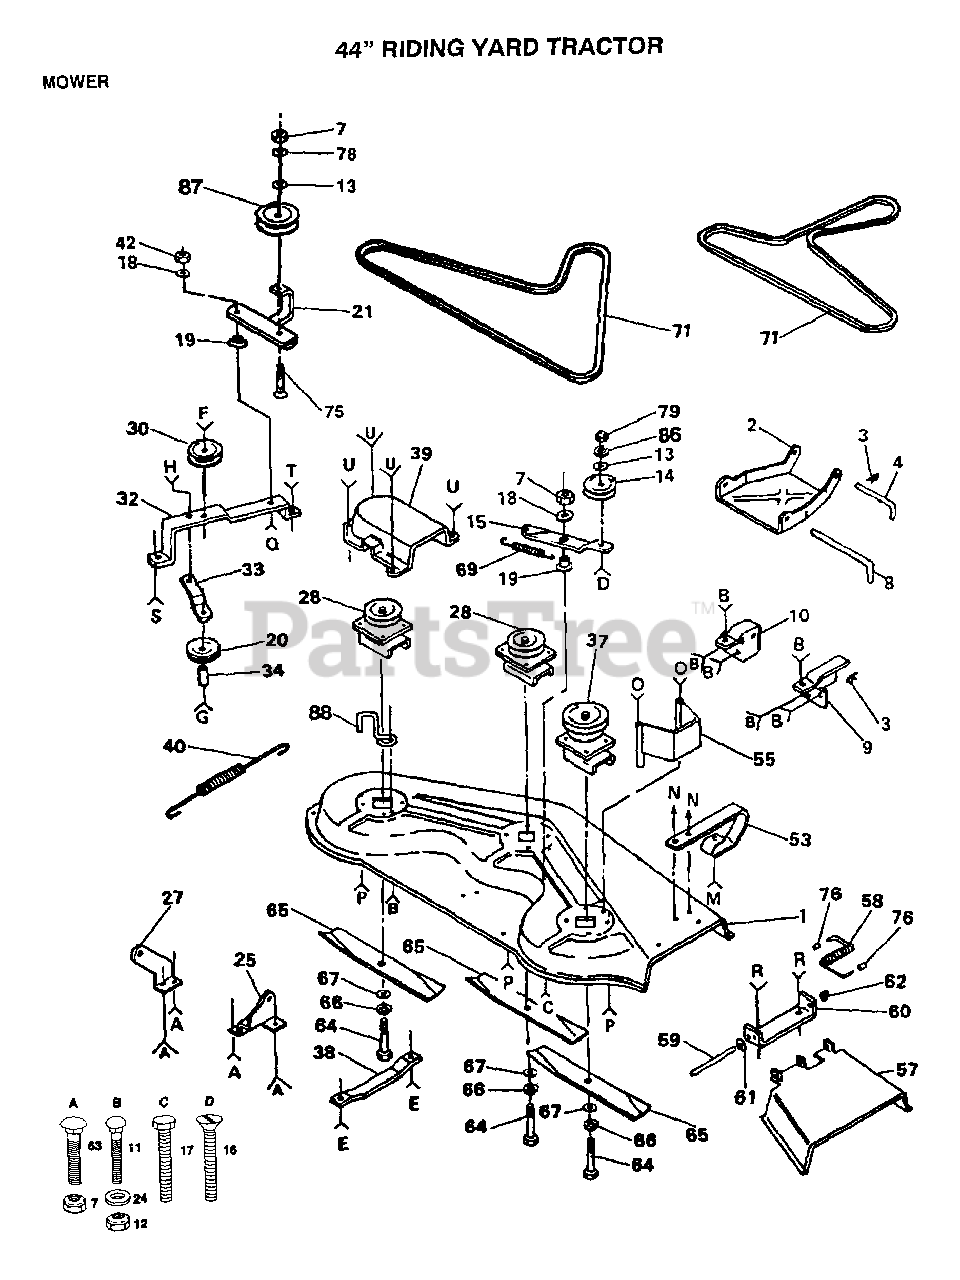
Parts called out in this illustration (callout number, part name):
2	LINK.PARALLEL
3	SPRING.RETAINER
4	"ROD, FRT. PARAL T"
8	HINGE PIN T
9	BRACKET RH YT
10	BRACKET LH YT
11	BOLT
13	WASHER
14	IDLER.FLAT.GTV
15	ARM-IDLER YT
16	SCREW YT
18	"WASHER, WEAR LT"
19	SPACER RETAINER
20	IDLER-FLAT T
21	ARM IDLER
24	WASHER M
25	BRKT SUSP REAR RH
27	BRKT SUSP REAR LH
30	IDLER-INSIDE T
32	"SUPPORT YT, BAR"
33	BRACE-IDLER YT
34	SPACER
38	RUNNER-LH M
39	GUARD YT
40	"SPRING.EXT.8.5"""
42	LOCKNUT
55	GUARD BELT HYT
57	DEFLECTOR SHIELD
59	ROD-HINGE T
61	WASHER
62	NUT PUSH M
63	BOLT
64	BOLT.3/8-24X1-1/2
67	WASHER
71	BELT-V.79.1.MWR
75	BOLT
76	CAP-SLEEVE LT
78	WASHER
79	NUT.HEX.3/8-16UNC
86	LOCKWASHER
87	PULLEY IDLER
88	BELT RETIANER
